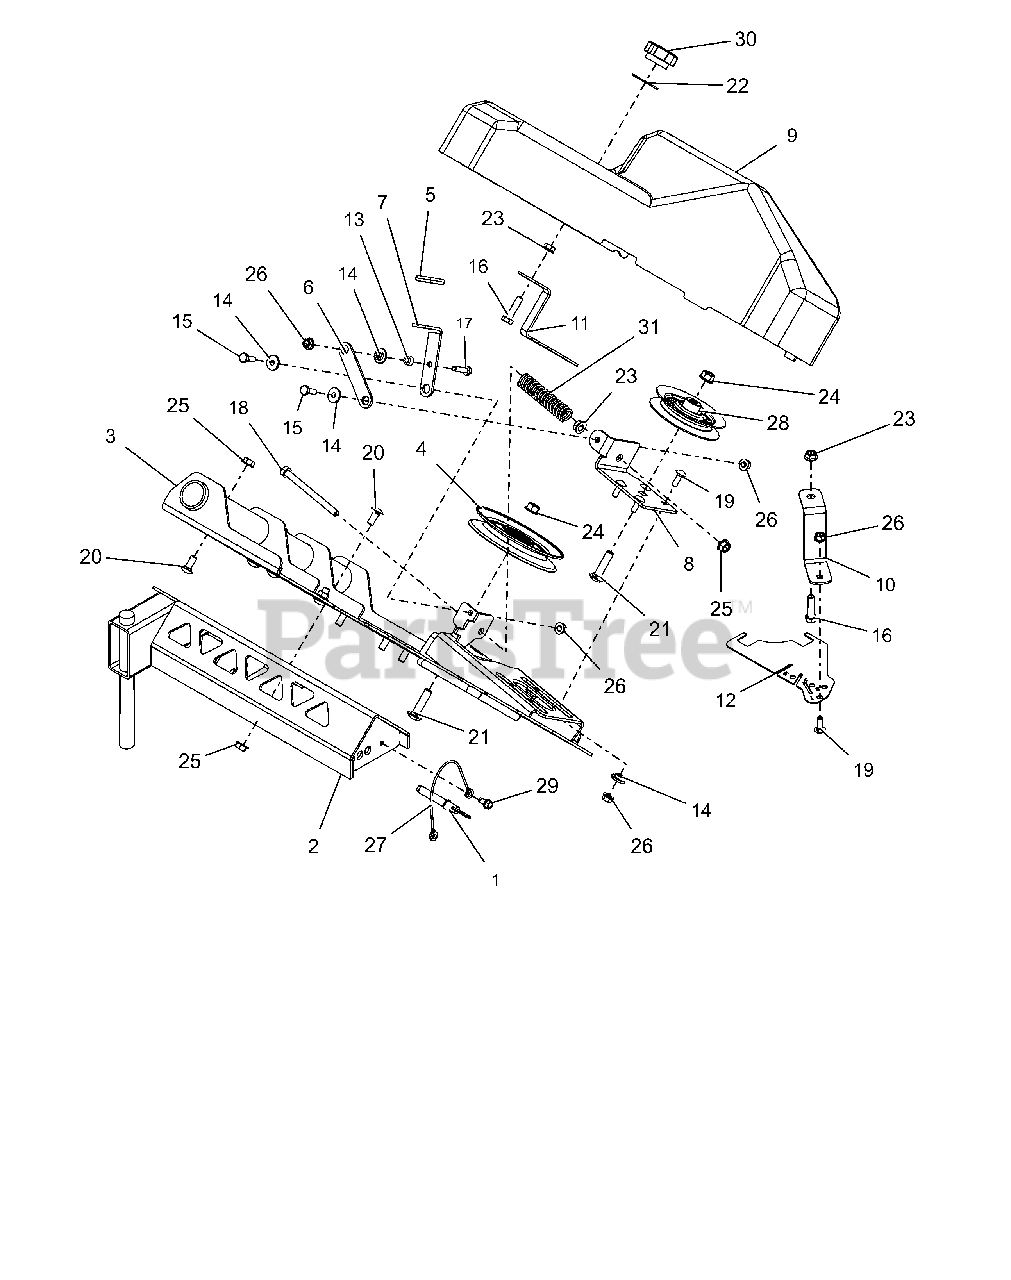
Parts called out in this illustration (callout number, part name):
1	PIN, SPRING BALL .375OD X 1.50
2	WLDMT, BLOWER MOUNT
3	WLDMT, BLOWER SPINDLE MNT (BLACK)
4	IDLER, V-5.00
5	GRIP, SEAT LEVER, GREY
6	LINK, TENSIONER
7	HANDLE, TENSIONER
8	PLATE, TENSION PULLEY MOUNTING
9	COVER, BELT HD BLOWER
10	PLT, DECK COVER MNT
11	PLT, COVER MNT
12	PLT, TEMPLATE BLK
13	BUSHING, .26 ID X .44 OD X .26
14	BSHG-FLG .265X.437X.250X.750
15	@BLT-HEX .25-20X.75 GR5 YWZC
16	@BLT-HEX .31-18X1.25 GR5 YWZC
17	@BLT-HEX .25-20X1.00 GR5 YWZC
18	@BLT-HEX .31-18X4.00 GR5 YWZC
19	@BLT-RDHDSQNK .25-20X.75 G5YZ
20	@BLT-RHDSSQNK .31-18X.75 G5YZ
21	@BLT-RHDSSQNK .38-16X1.50 G5YZ
22	WSHR-FL-STL .380X1.50X.062 YWZ
23	@NUT-SPNLK-FLG .312-18 YWZC
24	@NUT-LK-TOP-FLG .38-16 YWZC
25	@NUT-LK-TOP-FLG .31-18 YWZC
26	@NUT-LK-TOP-FLG .25-20 YWZC
27	CABLE, 12.0 LANYARD, NYLON
28	V-IDLER, 4.00X.38
29	SCR-TAP .25-20X.50 HWH TR YWZ
30	KNOB-CLAMPING, .312-18 NYLOC
31	SPRG, COMPRESSION
